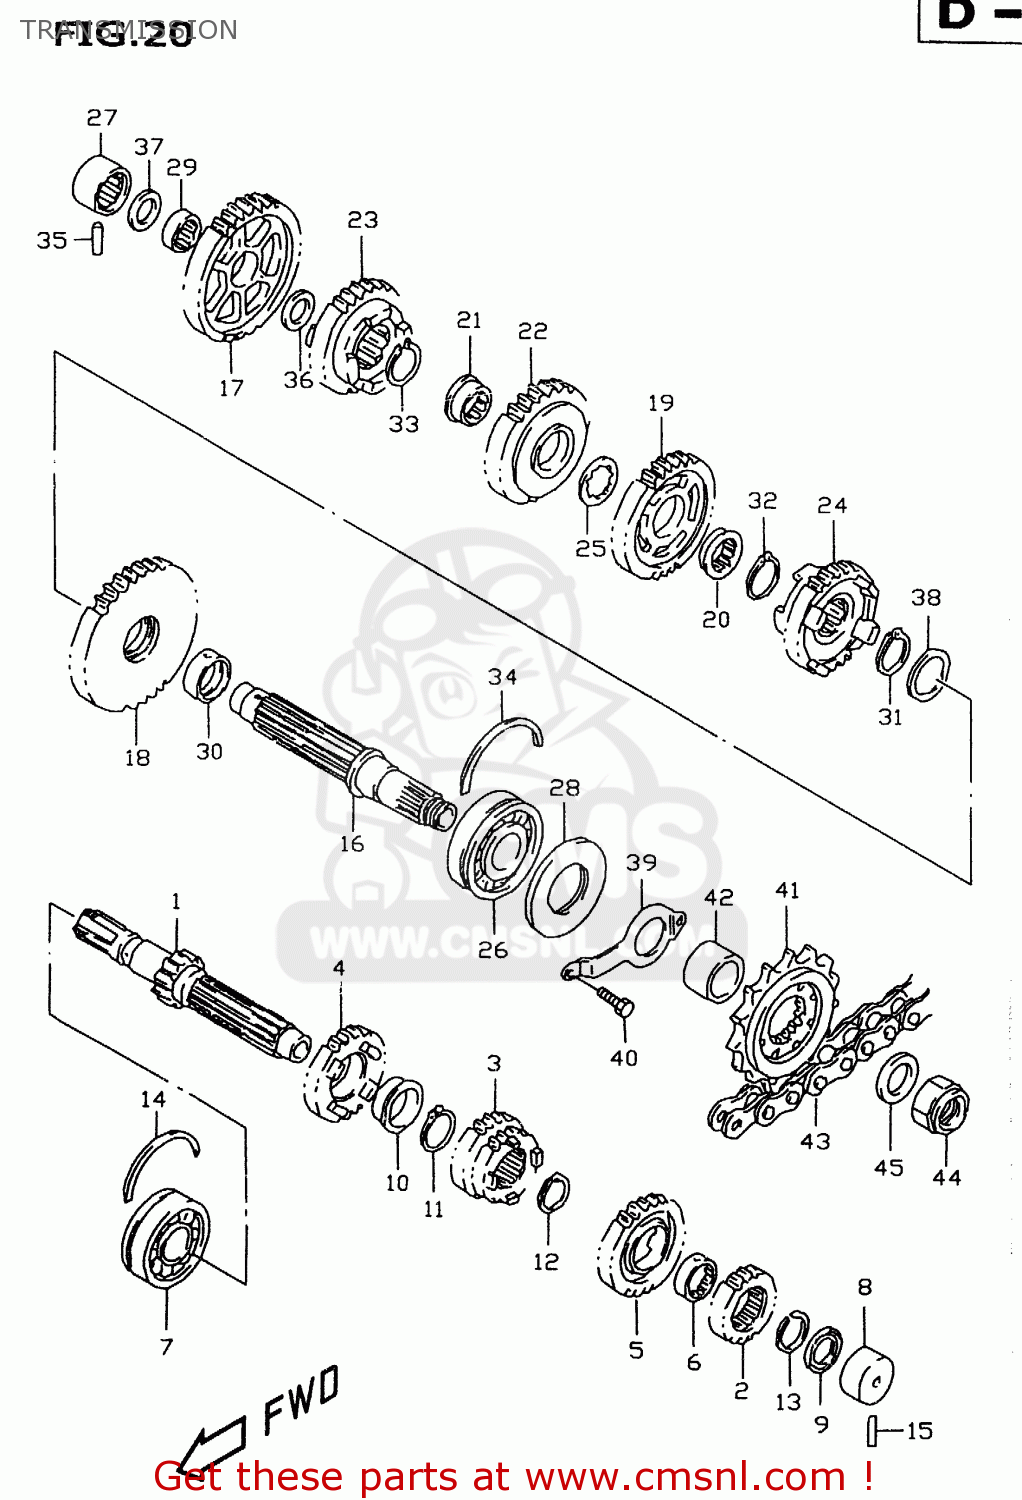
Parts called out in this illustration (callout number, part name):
1	SHAFT,COUNTER
2	GEAR,2ND DRIVE
3	GEAR,3RD & 4TH DRIVE
4	GEAR,5TH DRIVE
5	GEAR,6TH DRIVE
6	BUSH,6TH DRIVE GEAR
7	BEARING(25X62X17)
8	BEARING
9	SEAL,OIL(20X31.2X2.7)
10	BUSH(28X32X2)
11	CIRCLIP
12	CIRCLIP
13	CIRCLIP
14	C RING
15	PIN
16	SHAFT,DRIVE
17	GEAR,1ST DRIVEN
18	GEAR,2ND DRIVEN
19	GEAR,3RD DRIVEN
20	BUSH
21	BUSH
22	GEAR,4TH DRIVEN
23	GEAR,5TH DRIVEN
24	GEAR,6TH DRIVEN
25	WASHER,LOCK
26	BEARING(28X70X18)
27	BEARING(20X34X20)
28	SEAL,OIL(34.8X70X6)
29	BUSH(22X26X9)
30	BUSH(28X32X9.5)
31	CIRCLIP
32	CIRCLIP
33	CIRCLIP
34	C RING
35	PIN
36	SHIM(20X34X1)
37	SHIM(22X34X1)
38	SHIM(28X38X1)
39	RETAINER,CL PUSH ROD OIL SEAL
40	BOLT
41	SPROCKET,ENGINE(16T)
42	SPACER,ENG SPROCKET
43	CHAIN,DRIVE(DID525V9,108L)
44	NUT
45	WASHER(25X41X3)
